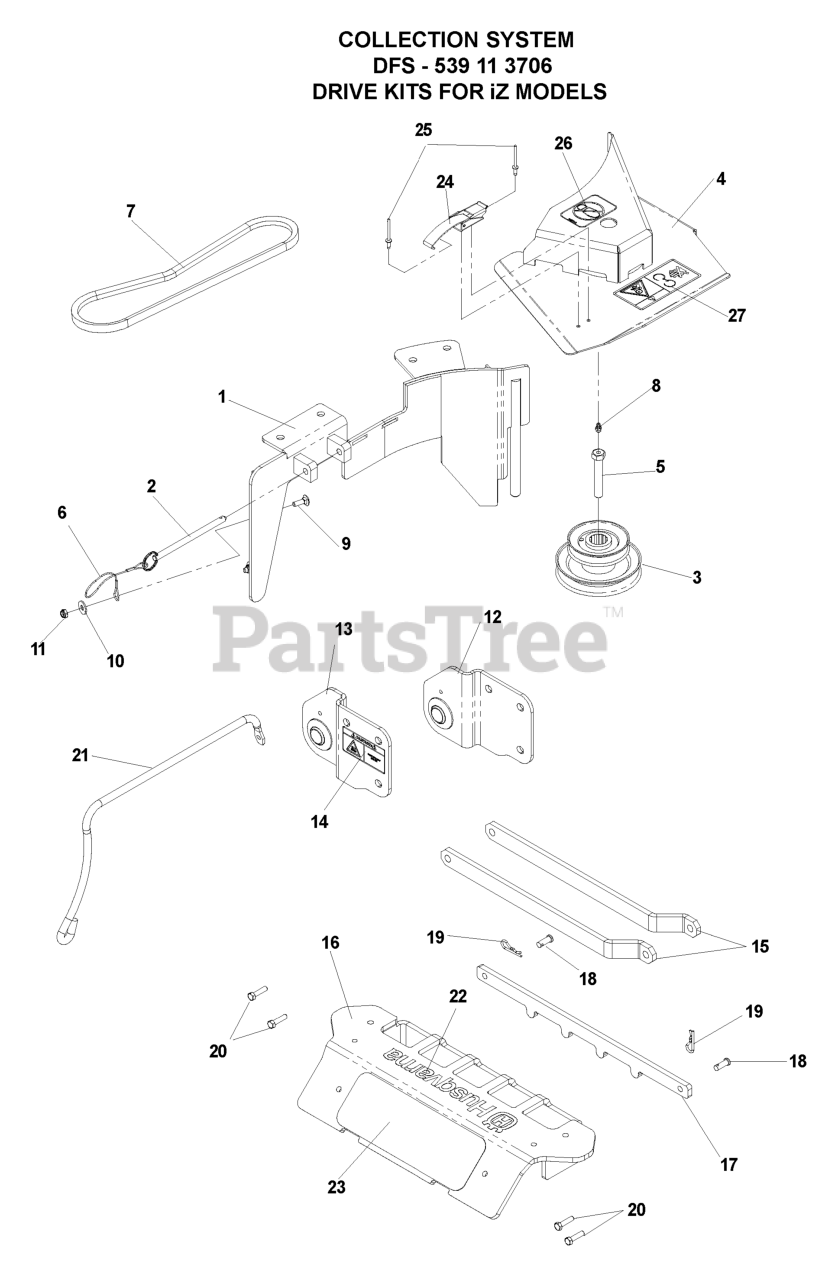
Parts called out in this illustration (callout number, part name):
1	BLOWER DECK PLATE
1	BLOWER DECK PLATE WLDMT, 52
1	BLOWER DECK PLATE WLDMNT, 61"
3	42/48 LG DBL HEX STACK PULLEY
3	52 LNG DOUBLE HEX STACK PULLEY
3	61 LNG DBL HEX STK PULLEY
4	BELT SHIELD ASSY 48"
4	BELT SHIELD ASSY 52"
4	BELT SHIELD ASSY 61"
5	HCS, 7/16-20 X 2 1/2, GR8
8	ZERK
9	RHSNB 1/4C X 3/4
10	WASHER 1/4 FLAT
11	JAM NUT 1/4C (2 2 PW01)
12	HITCH BRACKET WLD
13	HITCH BRACKET WLDMT, RT, MID
14	DECAL, HOT SURFACE
16	WEIGHT BAR, IZ
17	HOLD DOWN, WEIGHT BAR
18	CLEVIS PIN
19	RETAINER SPRING
20	HCS 5/16C X 1 1/4
21	HOSE SUPPORT
22	DECAL, HUSQ 12" BLUE
23	ANTI-SKID PAD
24	DRAW LATCH
25	RIVET, BLIND, 5/32 DIA
26	DECAL, NO STEP
27	DECAL, BELT DRIVE
539113706	Drive Kits (DFS)
